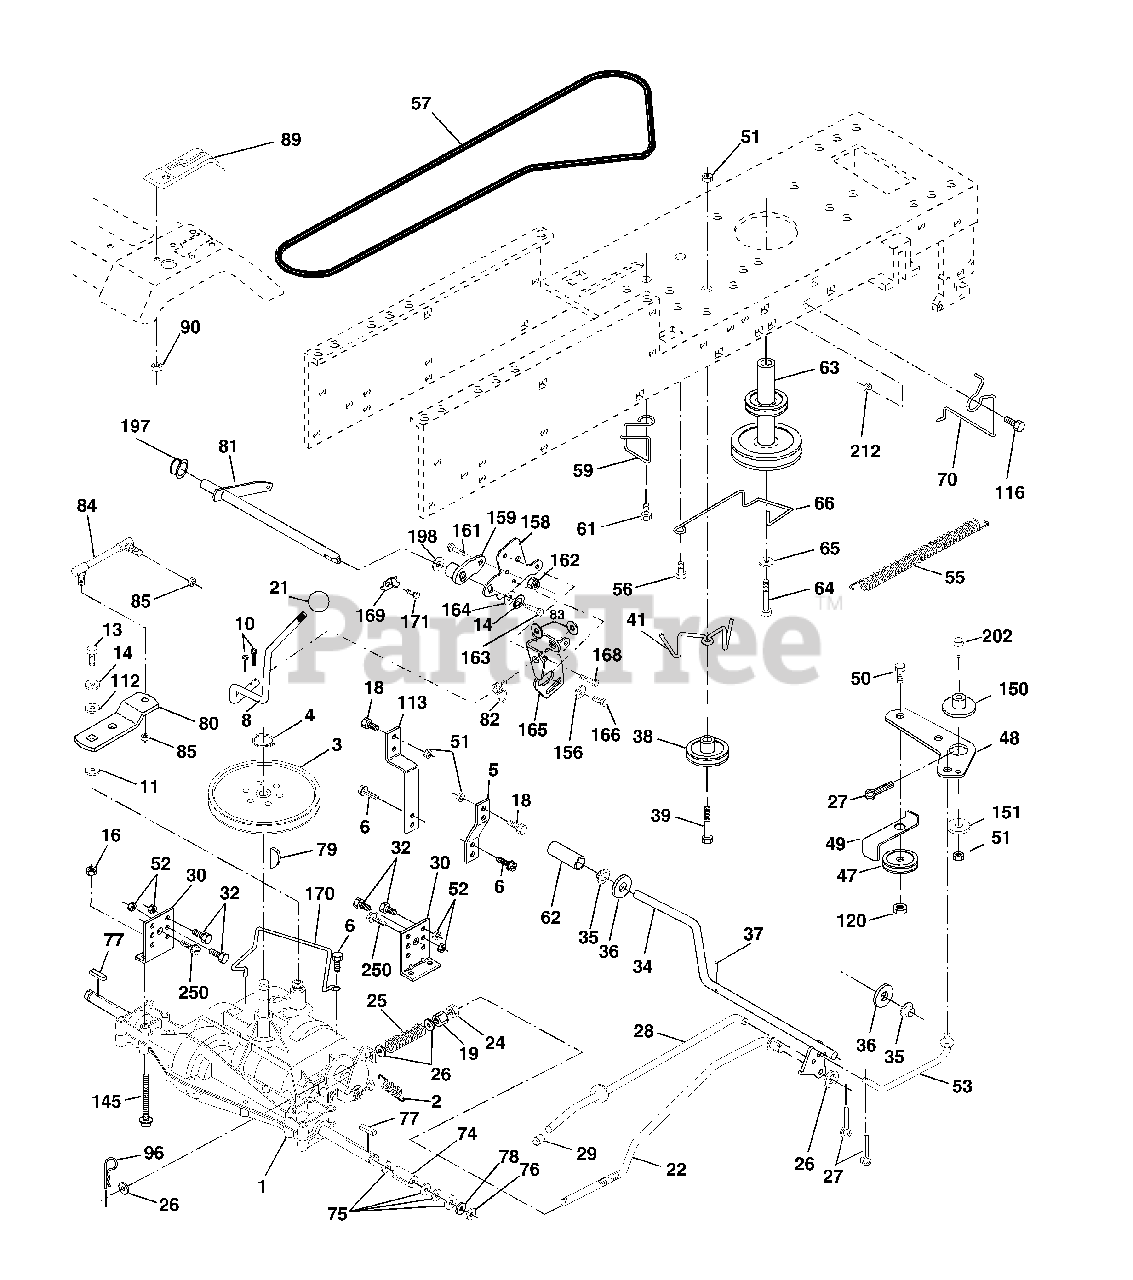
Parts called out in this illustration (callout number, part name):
2	Spring Return Brake T/a Zinc
3	Pulley Transaxle 18" tires
4	Ring Retainer # 5100-62
5	Strap Torque 30 Degrees
6	Screw 5/16-18 x 3/4
8	Rod Shifter Fender Adj Lt
10	Pin Cotter 1/8 x 1 Cad
11	Washer Plate Shf 388 Sq Hole
13	Bolt 1/4-28 Unf Gr 8 W/Patch
14	Washer Lock Hvy Helical 1/4
18	Bolt, Fin Hex 3/8-16 UNC x 1 Gr. 5
19	Nut Lock 3/8-16 Unc
22	Rod Brake Blk Zinc 26 840
24	Nut Hex Jam 3/8-16 Unc
25	Spring Rod Brake 2 00 Zinc
26	Washer 13/32 X 13/16 X 16 Ga
27	Pin Cotter 1/8 X 3/4 Cad
28	Rod Brake Parking
29	Cap Brake Parking
30	Bracket Mtg Transaxle
32	Bolt Hex Hd 5/16-18unc X 3/4
34	Shaft Asm Pedal Foot
35	Bearing Nylon Blk 629 Id
36	Washer 21/32 X 1 X 16 Ga
37	Pin Roll 3/16 X 1"
38	Pulley Idler Composite
39	Bolt Fin Hex 3/8-16unc X 3
41	Keeper Belt Retainer Idler
47	Pulley Idler V Groove Plastic
48	Bellcrank Asm
49	Retainer Belt Style Spring
50	Bolt Hex Hd 3/8-16unc X 1-1/2
51	Nut Crownlock 3/8-16 Unc
52	Nut Crownlock 5/16-18 Unc
53	Link Clutch
55	Spring Return Clutch 6 75
56	Screw 3/8-16 X 1-1/4
57	V-Belt Ground Drive
59	Keeper Belt Span Ctr
61	Screw 3/8-16 x .875
62	Cover Pedal Blk Round
63	Engine Pulley
64	Bolt Hex
65	Washer Lock Hvy Hlcl Spr 7/16
66	Keeper Belt Engine Foolproof
70	Guide Belt Mower Drive RH
74	Spacer Axle
75	Washer 25/32 X 1 1/4 X 16 Ga
76	E-ring #5133-75
77	Key Square 2 0 X 1845/ 1865
78	Washer 25/32 X 1-5/8 X 16 Ga
79	Key Woodruff
81	Shaft Asm Cross Tapered 20"t
82	Spring Torsion T/a
83	Washer 17/32 X 3/4 X 16 Ga
84	Link Transaxle
85	Nut Lock Center 1/4 - 28 FNTHD
89	Console Shift STLT
90	Nut Self-thd Wsh-hd 1/4 Zinc
96	Retainer Spring
112	Washer
113	Strap Torque Lh
116	Bolt Rdhd Sq Neck 3/8-16 x 1.00
120	Nut Lock Flg 3/8-16
145	Bolt Hex 5/16-18 Gr. 5
150	Spacer Retainer
151	Washer 13/32 x 2 x 10
156	Washer Srrted 5/16 ID x 1.125
158	Bracket Shift Mount
159	Hub Tapered Flange Shift lt
161	Bolt Rdhd Sqnk 1/4-20 x 3/4 Gr 5
162	Nut Crownlock 1/4-20 Unc
163	Bolt Hex Fin 1/4-20 Unc x 1 Gr 5
164	Washer 5/8 x .281 x 10 Ga
165	Bracket Pivot Lever
166	Screw 5/16-18 x 5/8
168	Bolt Shoulder 5/16-18 x .561
169	Plate Fastening Lt
170	Keeper Belt T/A
171	Screw Thdrol 3/8-16 x 1/2
197	Nyliner, Snap - in
198	Washer, Nyl.
202	Bolt, Carriage 3/8 - 16 x 1-3/4
212	Nut Flange Hex Lock
250	Screw 3/8-16 x .75
